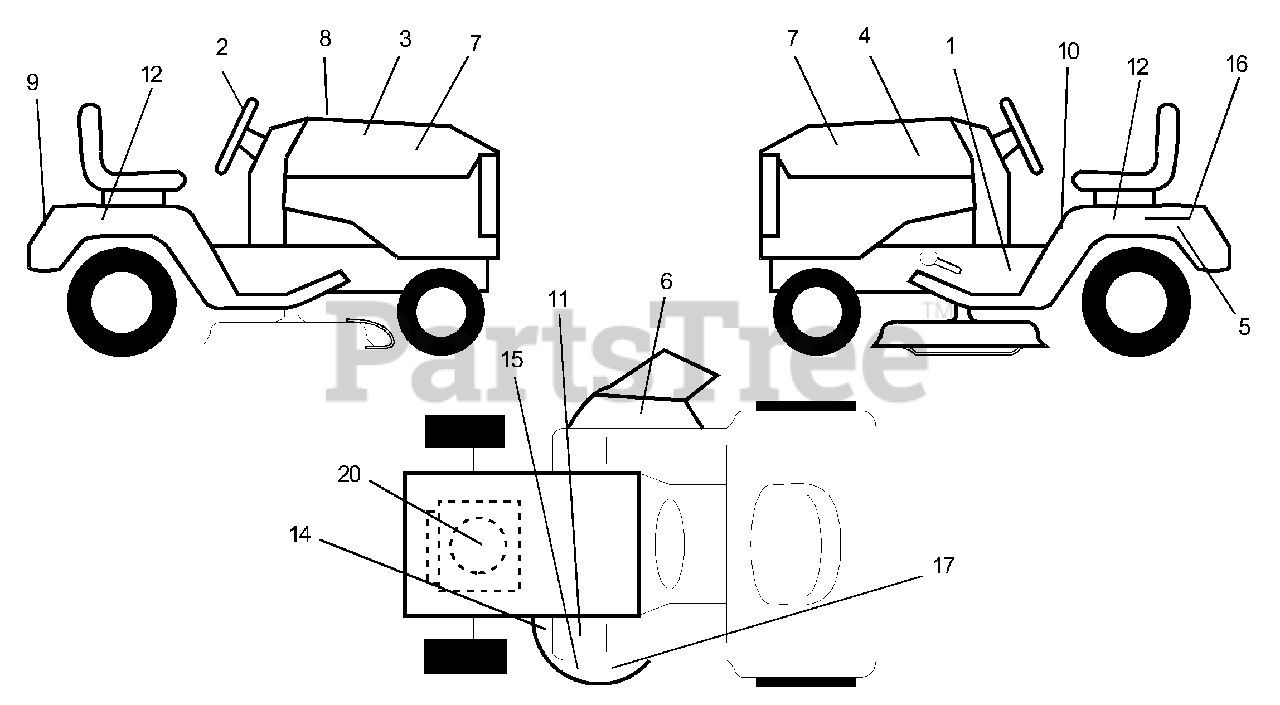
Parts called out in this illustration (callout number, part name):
1	Decal Instruction Operat English
2	Decal Ins Strg Wh
3	Decal Hood Rh
4	Decal Hood Lh
5	Decal Battery
6	Decal Warning
7	Decal Panel Side
8	Decal Replacement Parts
9	Decal Fender Logo
10	Decal Danger English
11	Decal Clutch/brake English
12	Decal Fender
14	Decal V-belt Schematic 42"
15	Decal Schematic
16	Decal Battery Danger/Poison
17	Decal Deck Enviro
20	Decal HP Engine
